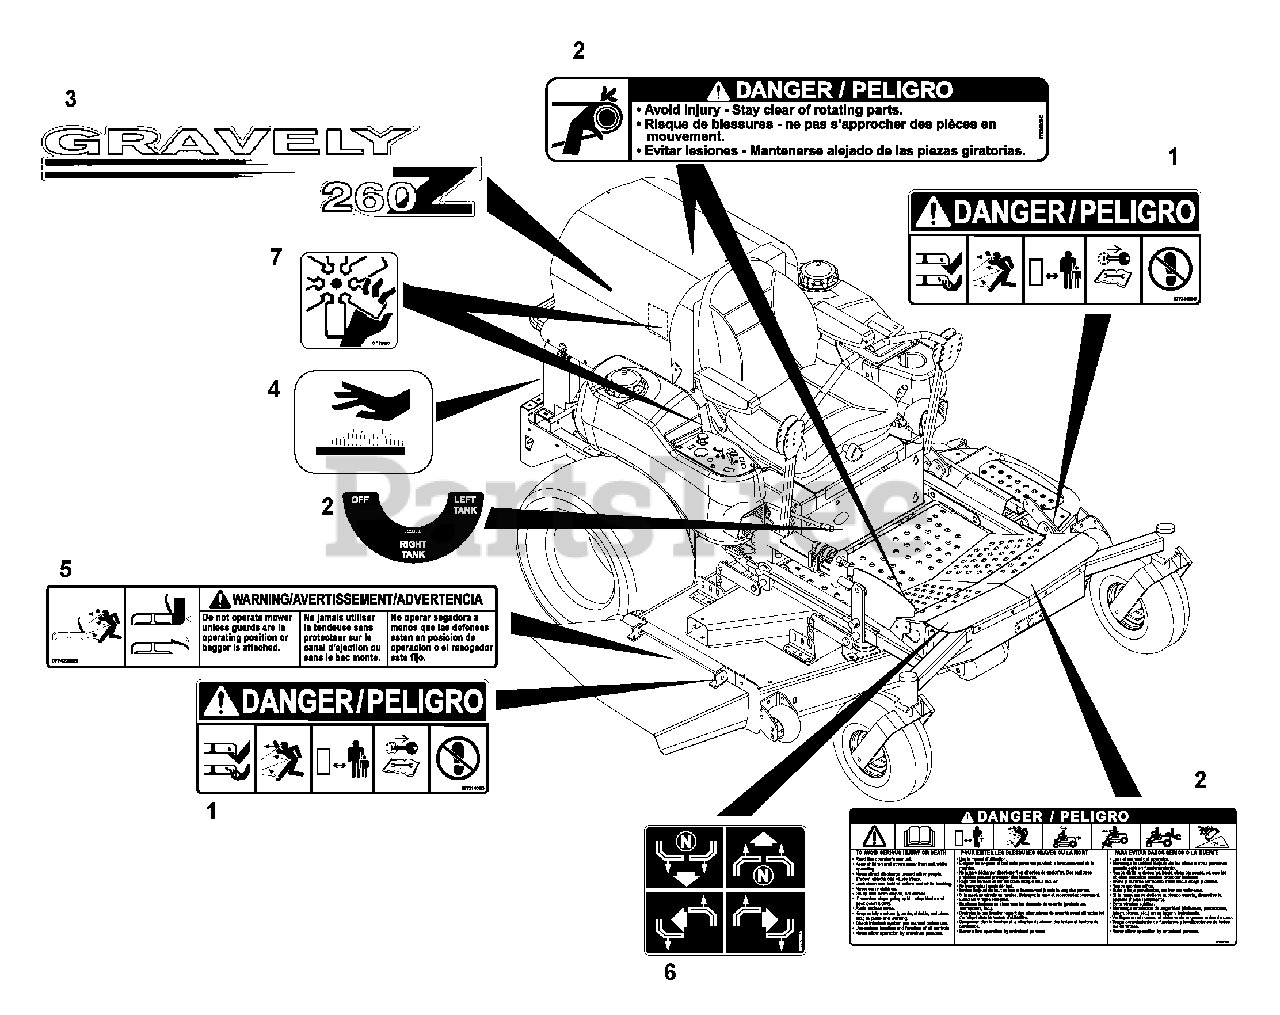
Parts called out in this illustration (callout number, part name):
1	Decal, Mower Pan Head Danger
2	Set, Decal-Common Danger/Fuel
3	Decal, PM-260Z Hood
3	Decal, PM-272Z Hood
4	Decal, Hot Surface
5	Decal, Warning
6	Decal, Instructional
7	Decal, Danger Fan
